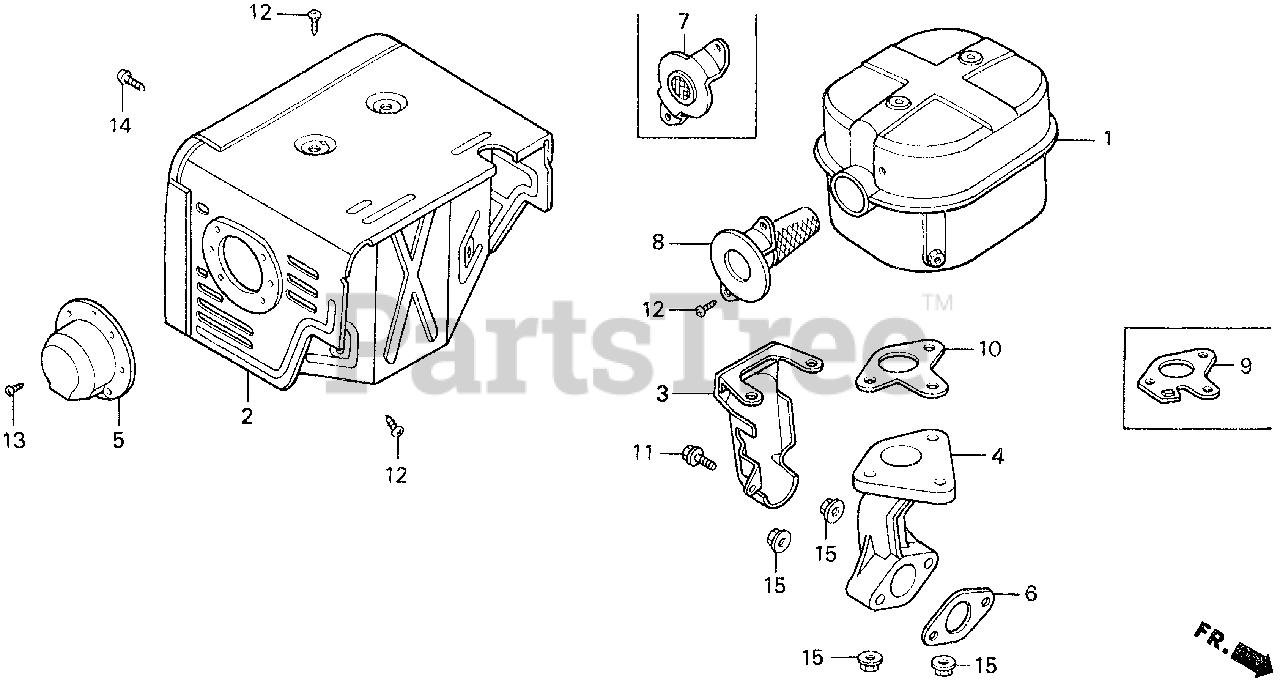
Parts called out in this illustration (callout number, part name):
1	MUFFLER
2	PROTECTOR, MUFFLER
3	PROTECTOR, EX. PIPE
4	PIPE, EX.
5	CAP, MUFFLER
6	GASKET, EX. PIPE
6	GASKET, EX. PIPE (WACKER)
8	ARRESTER, SPARK
9	GASKET, MUFFLER (ARRESTER)
11	BOLT, FLANGE (6X12) (CT200)
12	SCREW, TAPPING (5X8)
13	SCREW, TAPPING (4X6)
14	SCREW, PAN (6X6)
15	NUT, FLANGE (8MM)
